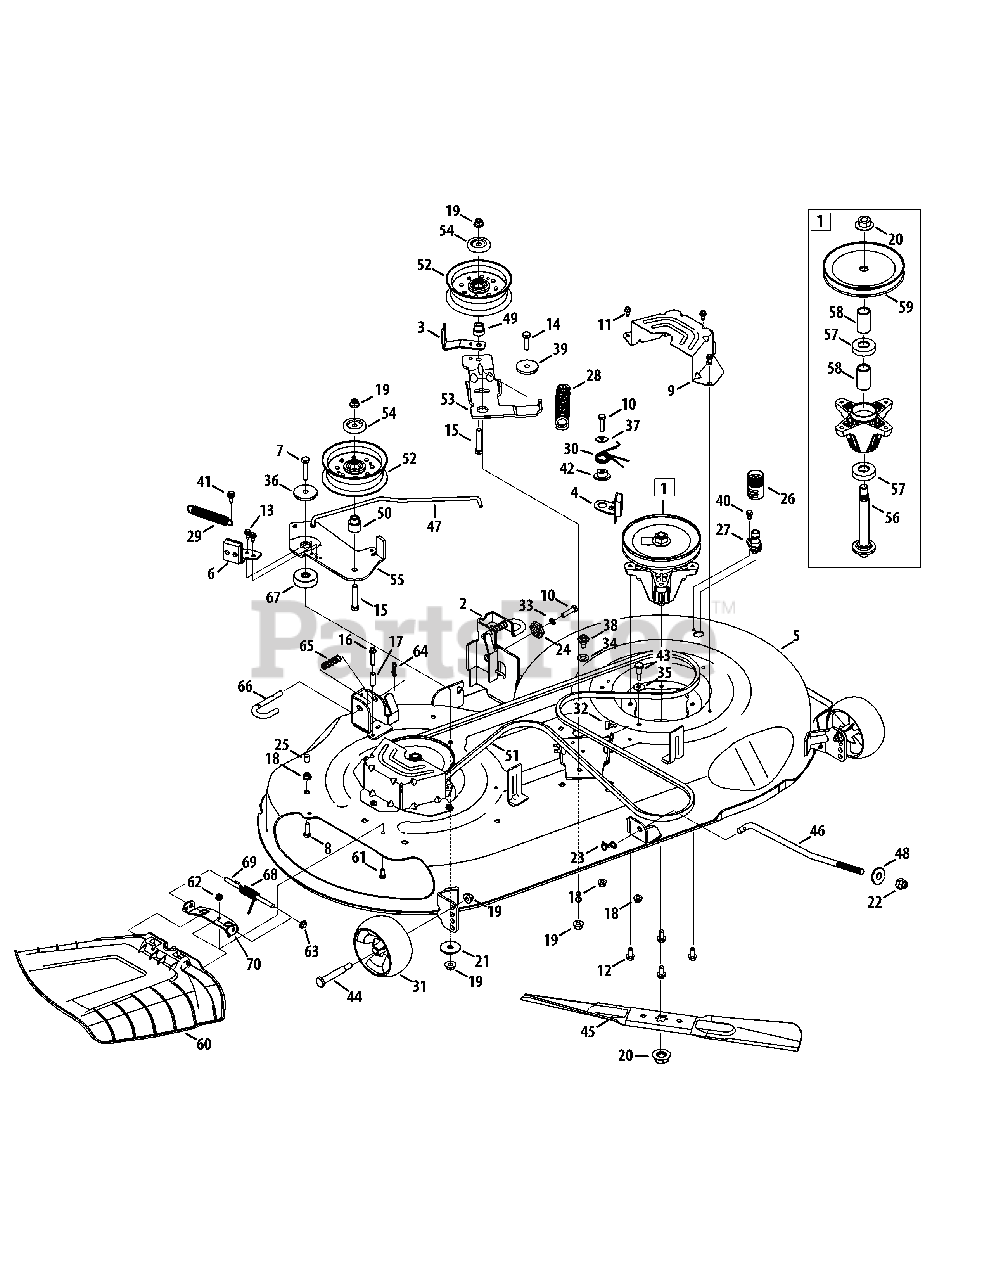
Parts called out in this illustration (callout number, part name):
1	Spindle Assembly, Pul 6.74 Dia
2	Bracket Assembly, Deck Hanger, LH
3	Belt Keeper
4	Brake Assembly, Deck, LH
5	Deck , 46t, 2w
6	Brake Assembly, Deck, RH
7	Hex Screw, 3/8-16 x 1.75
8	Hex Cap Screw, 5/16-18 x 1.00
9	Deck Belt Cover, 46
10	Hex Screw, 5/16-18, 1.25, Gr5, Std
11	Screw, Self-tapping, 1/4-20, 0.500
12	Screw, 5/16-18 x 0.750
13	Screw, M6-1 x .625
14	Hex Screw, 3/8-16 x 1.25
15	Hex Head Screw, 3/8-16 x 2.00
16	Screw, 1/4-20 x 1.25
17	Spacer, .260 x .375 x 1.030
18	Nut, Flange Lock, 5/16-18, Nylon
19	Nut, Flange Lock, 3/8-16, Nylon
20	Nut, Flange, 5/8-18
21	Flat Washer, .406 x 1.500 x .105
22	Flange Lock Nut, 1/2-13
23	Bow-Tie Cotter Pin
24	Gear, Deck Adjustment
25	Cap, .290 x .500
26	Water Nozzle Adapter
27	Deck Wash Nozzle
28	Spring, Extension, 1.05 X 6.346
29	Spring, Extension, .750 x .477
30	Torsion Spring, LH
31	Wheel, Deck, 5.0 Dia Ball
32	Bumper, .62 Dia X .3
33	Washer, Lock, 5/16, Regular Duty
34	Washer, Flat, .474 x .879 x .064
35	Washer, Flat, .343 X .880 X .062
36	Shoulder Spacer, .970 X .190
37	Flat Washer, .344 x 1.0 x .063
38	Shoulder Spacer, .43 x .29, 5/16-18
39	Shoulder Spacer, .8840 X .190
40	Shoulder Screw, 1/4-20 x 0.50
41	Shoulder Screw, .368 x .113 x 1/4-20
42	Shoulder Spacer, .75 x .145
43	Shoulder Screw, .437 Dia. X .54
44	Bolt, Shoulder, .496 x 2.50, 3/8-16
45	Blade, Cut, 23.25" 2-In-1
46	Rod, Lift, Deck, Medium
48	Pivot Cup, Deck List
49	Shoulder Spacer, Idler
50	Shoulder Spacer, Pivot Idler
51	Belt, V-Typ, A Sec
52	Pulley, Idler, 4.50"Dia
53	Bracket, Idler, 46" Lh
54	Pulley Cap
55	Deck Idler Bracket
56	Spindle Shaft, 6.05 LG.
57	Ball Bearing, .787ID X 1.85 ODX.551
58	Spacer, .792 X 1.060 X 1.860 LG
59	Deck Pulley, 6.74 DIA
60	Chute Deflector Assembly
61	Hex Cap Screw, 1/4-20 x .62
62	Nut, Flange Lock, 1/4-20, Nylon
63	Push Cap
64	Bow-Tie Cotter Pin, 72
65	Spring, Compression, .535 x 1.751
66	Rod, Deck Release
67	Spacer, .385 ID x 1.75 OD x .585
68	Spring, Torsion, .440 ID x 1.75
